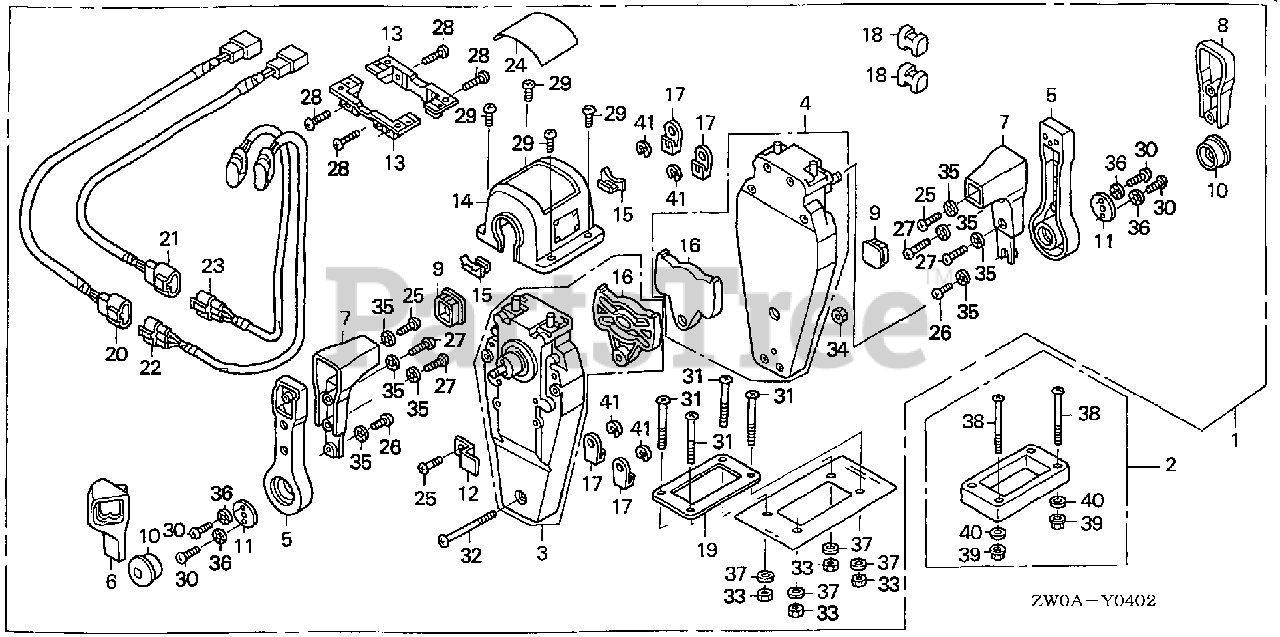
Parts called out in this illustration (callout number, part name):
1	BOX KIT, REMOTE CONTROL
2	SPACER KIT, REMOTE CONTROL BOX
3	HOUSING ASSY., L. (INNER)
4	HOUSING ASSY., R. (INNER)
5	HANDLE, REMOTE CONTROL
6	COVER, L. GRIP
7	GRIP, REMOTE CONTROL HANDLE
8	COVER, DUAL GRIP
9	CAP, GRIP
10	BUTTON, THROTTLE
11	PLATE, HANDLE
12	PLATE, CABLE CLAMP
13	BRACKET, REMOTE CONTROL
14	HOUSING, DUAL REMOTE CONTROL
15	HOUSING, LEAD
16	PLATE, DWELL
17	TERMINAL, CABLE
18	SPACER, CABLE CLAMP
19	GASKET, DUAL
20	SUB-HARNESS ASSY., POWER
21	SUB-HARNESS ASSY., POWER
22	SWITCH ASSY., POWER TRIM-TILT
23	SWITCH ASSY., POWER TRIM-TILT
24	MARK, REMOTE CONTROL (DUAL)
25	SCREW, PAN (5X16)
26	SCREW, PAN (5X10)
27	SCREW, PAN (5X20)
28	SCREW, PAN (5X18)
29	SCREW, PAN (4X10)
30	SCREW, PAN (6X18)
31	SCREW, PAN (5X40)
32	SCREW, PAN (5X55)
33	NUT, HEX. (5MM)
34	NUT, HEX. (5MM)
35	WASHER, LOCK (5MM)
36	WASHER, LOCK (6MM)
37	WASHER, PLAIN (5MM)
38	SCREW, PAN (5X65)
39	NUT, HEX. (5MM)
40	WASHER, PLAIN (5MM)
41	E-RING (6MM)
